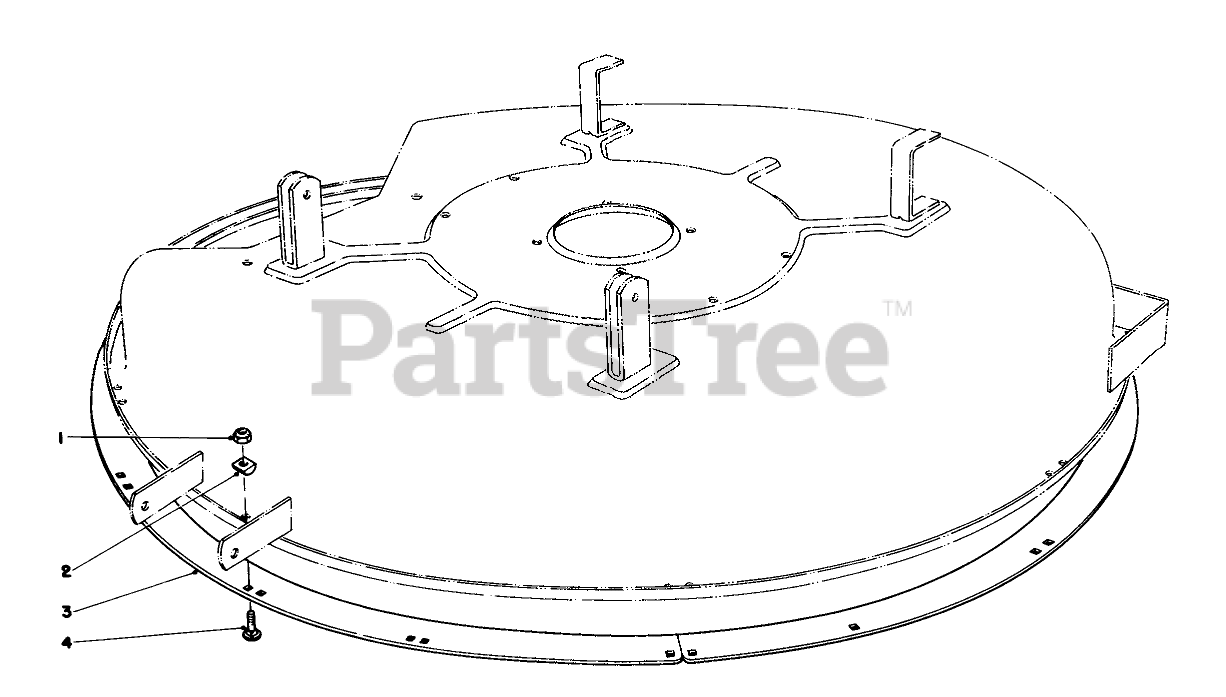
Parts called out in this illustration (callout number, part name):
1	NUT-LOCK, NI
2	Spacer-Deck Ring
3	DECK RING B
4	BOLT-CARR
